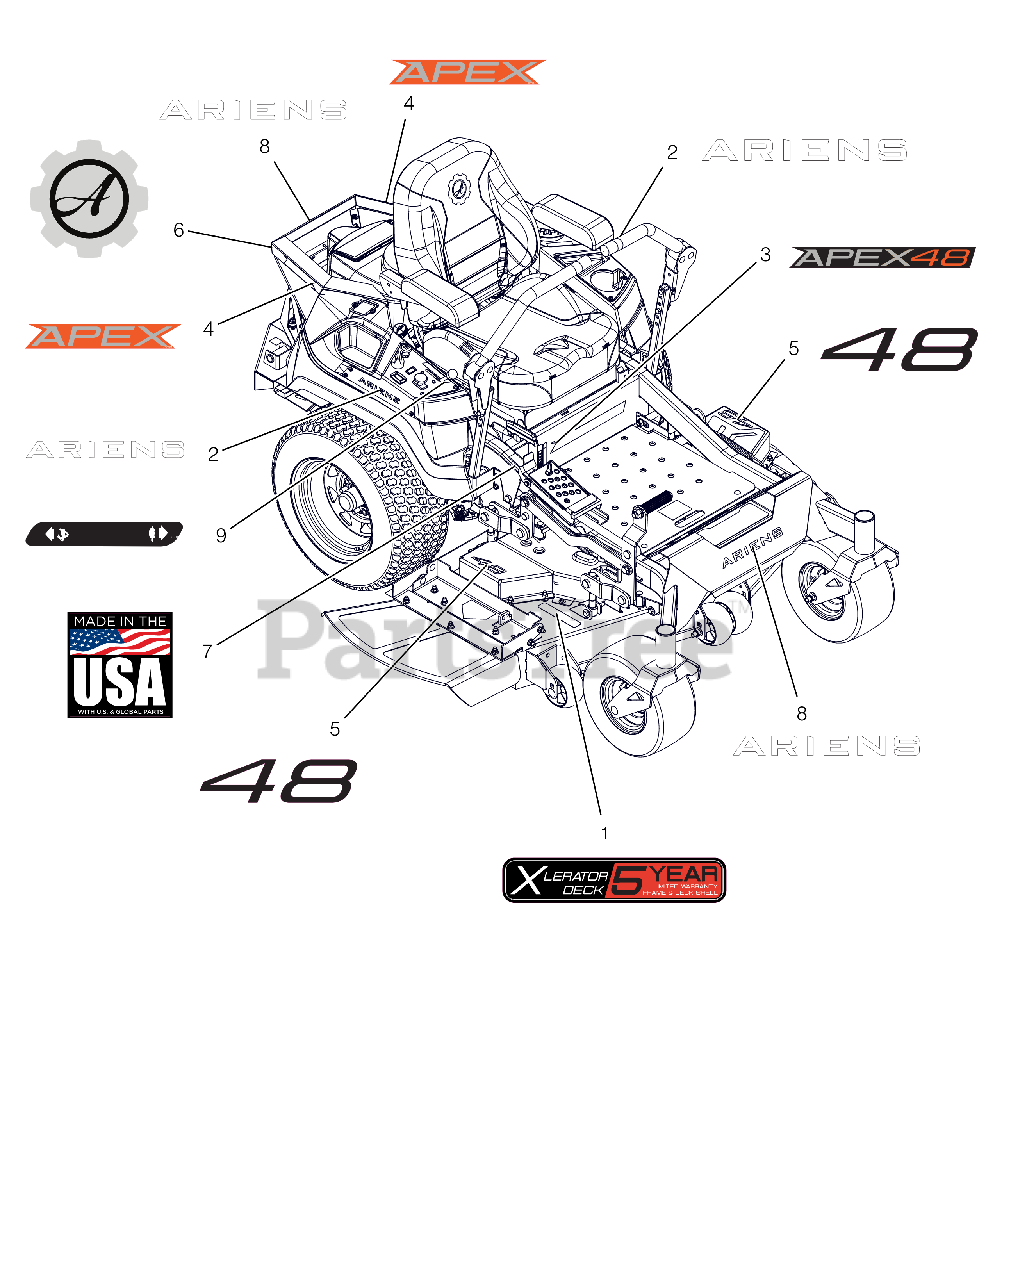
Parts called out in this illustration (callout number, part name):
1	DECAL-ARIENS, DECK 5 YEAR
2	DECAL, ARIENS (6.50")
3	DECAL, 48" APEX KICKPLATE
4	DECAL, APEX FENDER
5	DECAL, BLACK 48
6	DECAL, ARIENS-GEAR BADGE -THK
7	DECAL, MADE IN USA
8	DECAL - ARIENS 9.625"
9	DECAL, DASH DECAL
